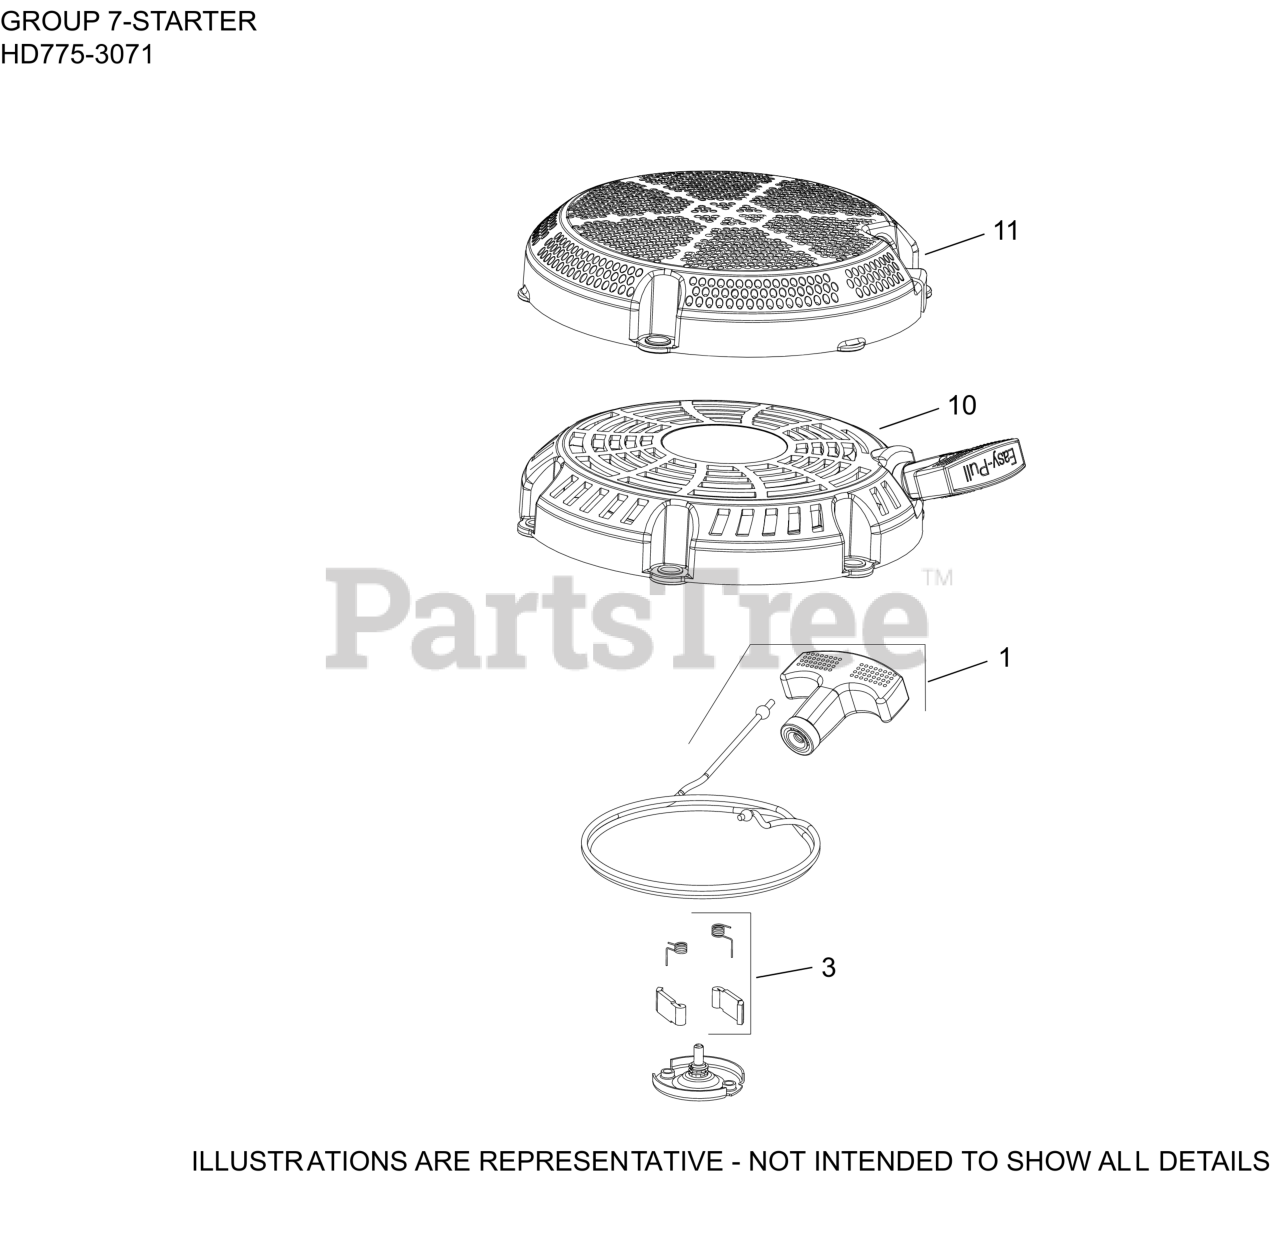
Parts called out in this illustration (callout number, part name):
1	KIT, STARTER ROPE W/HANDLE
3	KIT, PAWL REPAIR
10	STARTER ASSEMBLY, RETRACTABLE
11	INSERT, DEBRIS SCREEN
